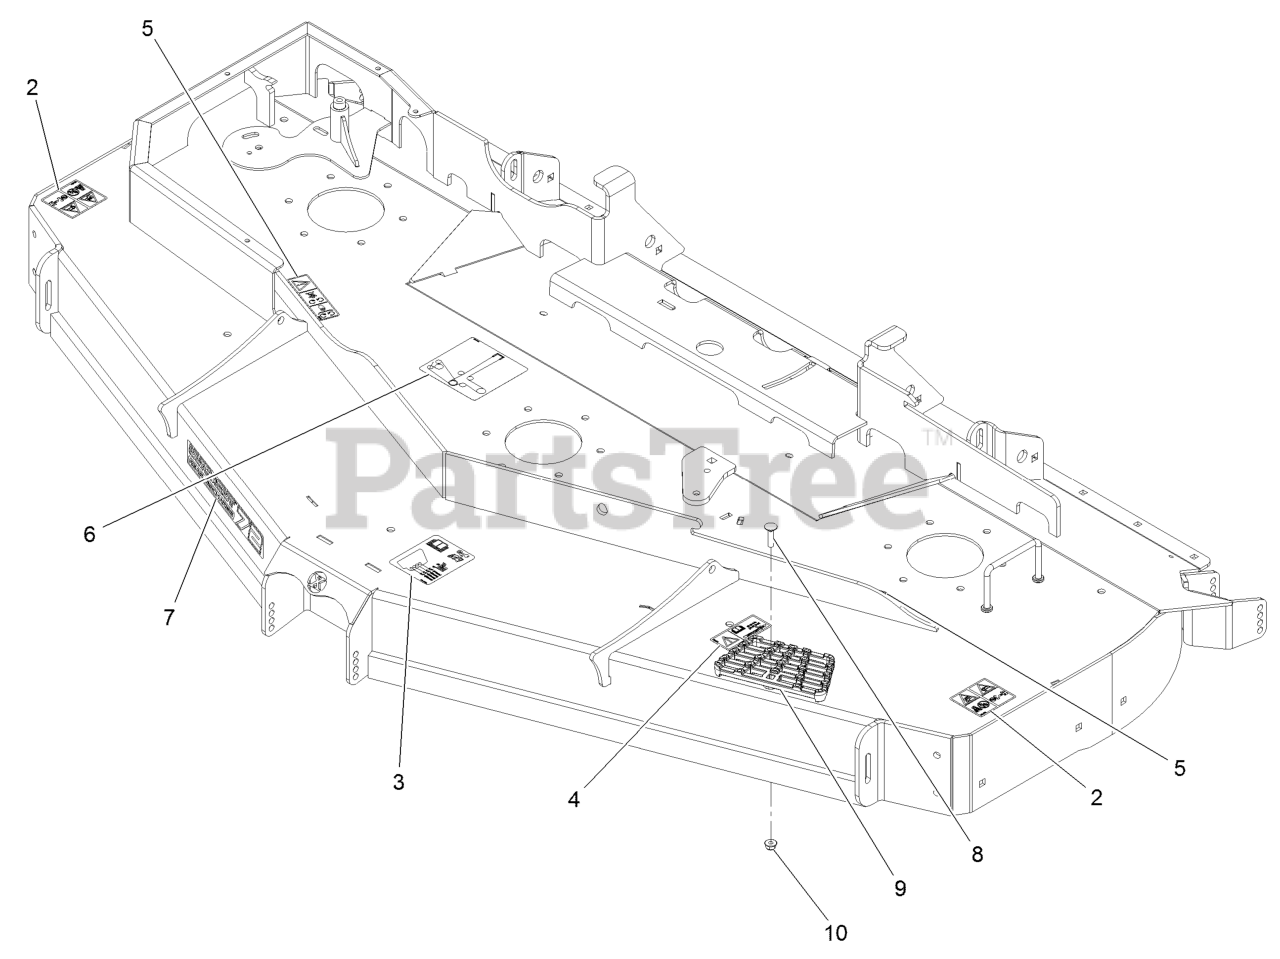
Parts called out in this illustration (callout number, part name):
3	DECAL-ROLLER, ANTI-SCALP
4	DECAL-BOLT TORQUE
5	DECAL-COVER, MISSING
6	DECAL,BELT ROUTING RD DEC
7	Decal, 72Rd
8	Bolt-Carriage 5/16-18 X 1 1/4
9	STEP-DECK
10	NUT-HF, NI
